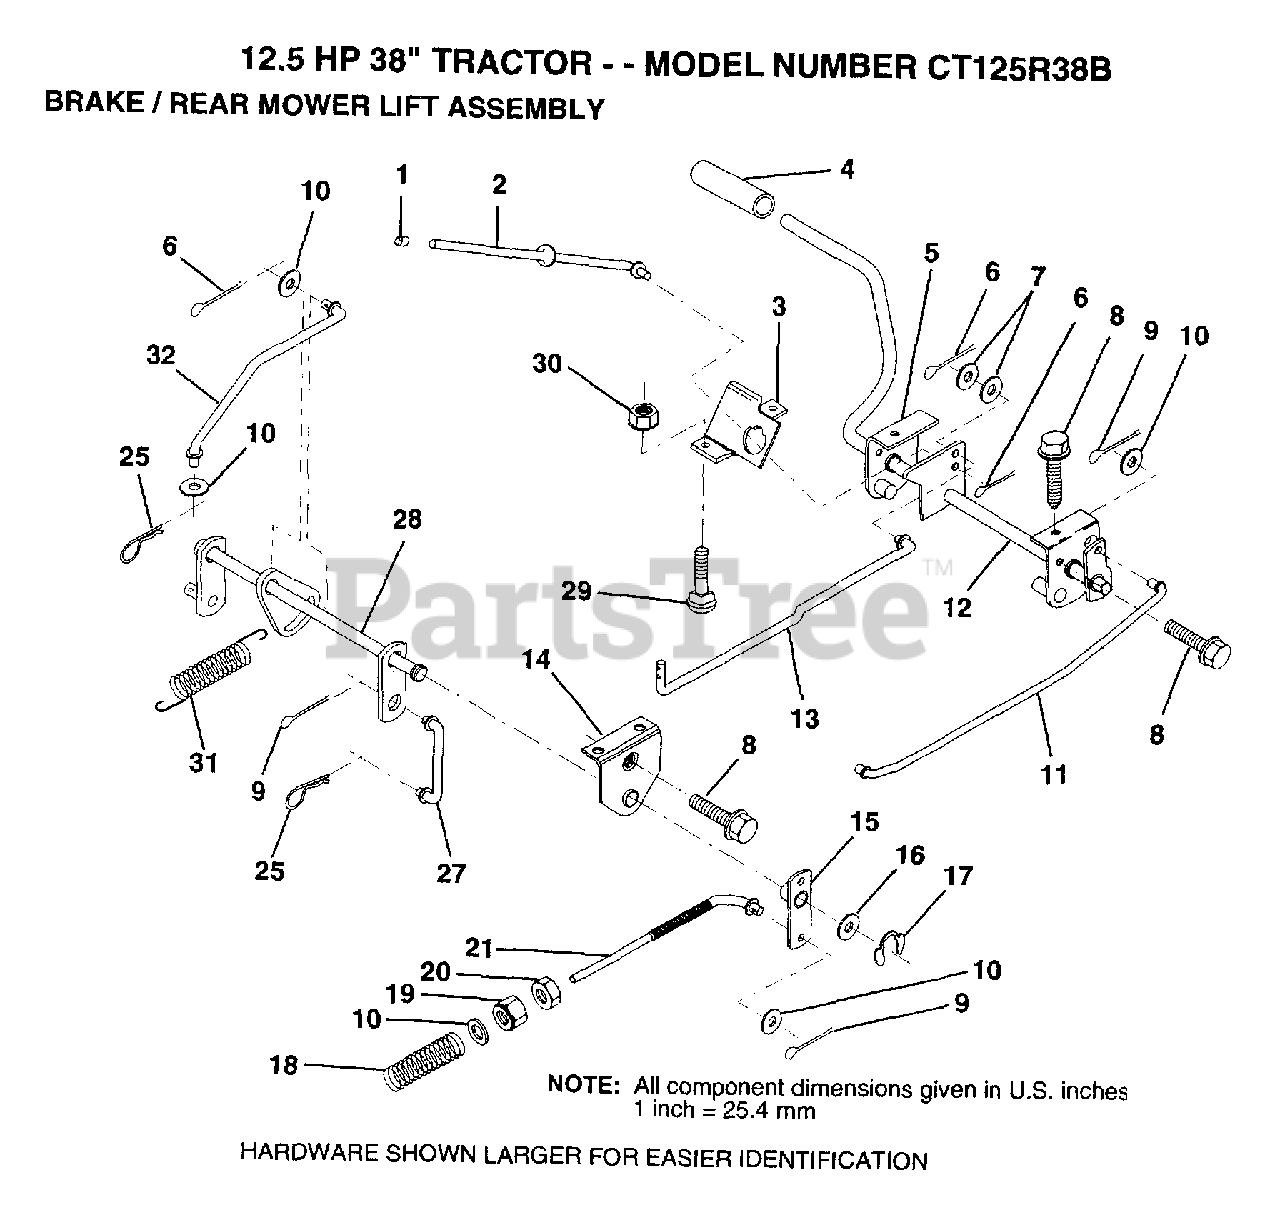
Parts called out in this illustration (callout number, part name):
2	"ROD,PARK BRAKE"
3	"BRKT,PARK BRAKE"
4	PEDAL COVER T
5	BRK ASM CLUT LH
7	WASHER
8	SCREW LT
9	COTTER PIN
10	WASHER
11	"ROD,FRT BRAKE"
12	ASM CLUTCH/BRK PD
13	"ROD,CLUTCH"
14	"BRKT,LIFT SHAFT"
15	BRAKE PIVOT ARM
16	WASHER T
17	KLIP RING
18	SPRING ROD LT
19	NUT
25	SPRING.RETAINER
27	LINK LIFT REAR LR
28	LIFT ASM MWR RE
31	COUNTER SPRING
32	LINK LIFT LEVER
